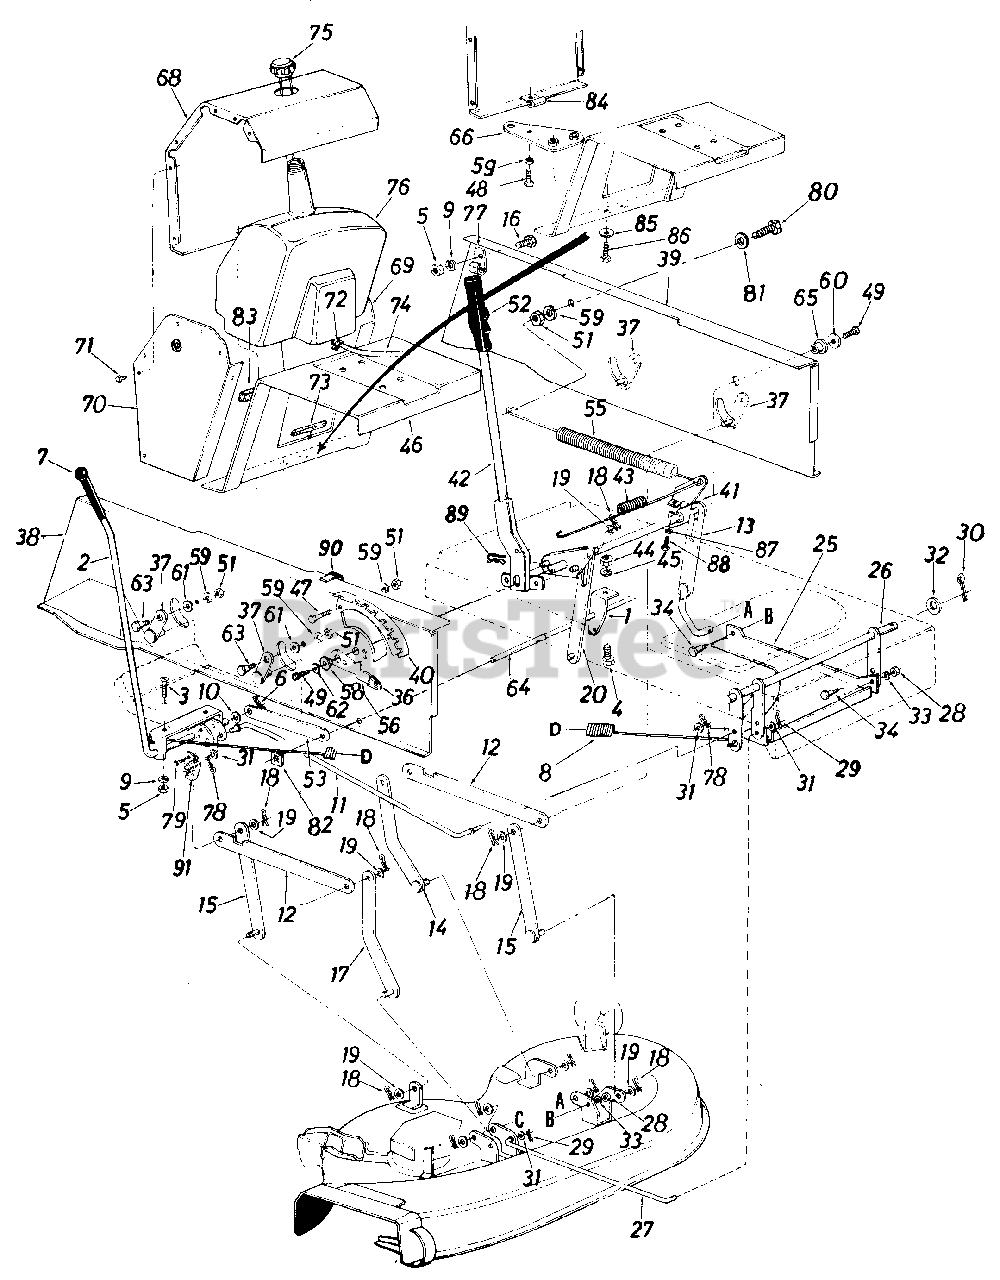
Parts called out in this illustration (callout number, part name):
1	Spring Hanger Bracket
2	Deck Engagement Lever Ass'y.
3	Truss Mach. Scr. 5/16-18 x .75" Lg.*
4	Hex Bolt 1/4-20 x .62" Lg.*
5	Hex Nut 5/16-18 Thd.*
6	Cotter Pin 3/32" Dia. x 1.00" Lg.
8	Ext Spring .99" O.D. x 22" Lg.
9	L-Wash. 5/16" I.D.*
10	Fl-Wash. .510" I.D. x 1.0" O.D.
11	Drive Deck Control Rod 1 2.5
12	Conneting Rod 3/16 x 1 x 12.5
13	Deck Lift Link Ass'y.
14	Deck Hanger Link Ass'y.-Rear L.H.
15	Deck Hanger Link Ass'y.
16	Hex Bolt 5/16-18 x .75" Lg.*
17	Deck Hanger Link Ass'y.- Front R.H.
18	Inter. Cotter Pin 1/2" Dia.
19	Fl-Wash. .531 I.D. x.93" 0. D.
20	Link Deck Lifting Ass'y.
25	Diagonal Brace
26	Stabilizer Shaft Ass'y.
27	Stabilizer Rod
28	Hex Nut 3/8-16 Thd.*
29	Cotter Pin 3/32" Dia. x 1.0" Lg.
30	Cotter Pin 1/8" Dia. x 1.25" Lg.*
31	Fl-Wash. .385" I.D. x .620" O.D.
32	Fl-Wash. .635" I.D. x 1.12" 0. D.
33	L-Wash. 3/8" I.D.*
34	Shoulder Bolt 3/8-16
36	Knob-Height Adj.
37	Pivot Link Ass'y.
38	Side Panel Upper Frame-R.H.
39	Side Panel Upper Frame-L.H.
40	Index Brkt.
41	Lift Shaft Ass'y.
42	Lift Handle Brkt. Ass'y.
43	Ext. Spring
44	Hex Nut 1/4-20 Thd.*
45	L-Wash. 1/4" I.D.*
46	Hitch Plate
47	Hex Bolt 5/16-18 x .75" Lg.
48	Hex Bolt 5/16-18 x 1.00" Lg.(Grade 5)
49	Hex Wash. TT-Tap Scr. 5/16-18 x .62" Lg.
51	Hex Nut 5/16-18 Thd.
52	Grip
53	Link 1.0" x 7.5" x .19
55	Ext. Spring .99" Dia. x 11.00" Lg.
56	Deck Lift-Down Stop
58	Flange Brg. .630" I.D.
59	L-Wash. 5116" I.D.
60	Fl-Wash. .344" I.D. x 1.125" O.D. x .125
61	Bell-Wash. .325" I.D. x .930" O.D. x .045"
62	Fl-Wash. .344" I.D. x 1.125" O.D.
63	Shld. Bolt .437" Dia. x .180
64	Running Board Rod
65	Flange Brg. .632" I.D.
66	Hitch Bar Ass'y.
68	Gas Tank Housing-Main Panel
69	Side Panel-L.H.-Gas Tank
70	Side Panel-R.H.-Gas Tank
71	Truss Mach. B-Tapp Scr. #10 x .50" Lg.
72	Hose Clamp-.406" Dia.
73	Trim Strip-5" Lg.
74	Gas Line-44" Lg.
75	Gas Tank Cap
76	Gas Tank
77	Hose Clamp
78	Cotter Pin 3/32" Dia. x .75" Lg.
79	Hex Wash. Hd. Tap Scr. 1/4 x.50" Lg.
80	Hex Bolt 5/16-18 x 1.50" Lg.
81	Fl-Wash. .344" I.D. x .875" 0. D.
82	Speed Nut for .500" Dia. Stud
83	Foam Strip 3/8" x 1-1/8" x 1-1/2" Lg.
84	U-Nut 5/16-18 Thd.
85	Bell-Wash. .385" I.D. x .88"
86	Hex Wash. Tap-Scr. 3/8-16 x .75" Lg.
87	Hex Jam Nut 5/16-18 Thd.(Grade 5)
88	Hex Wash. Hd. Tap Scr. 5/16-18 x 1" Lg.
89	Internal Cotter Pin 3/8" Dia.
90	Clamp
91	Safety Switch
